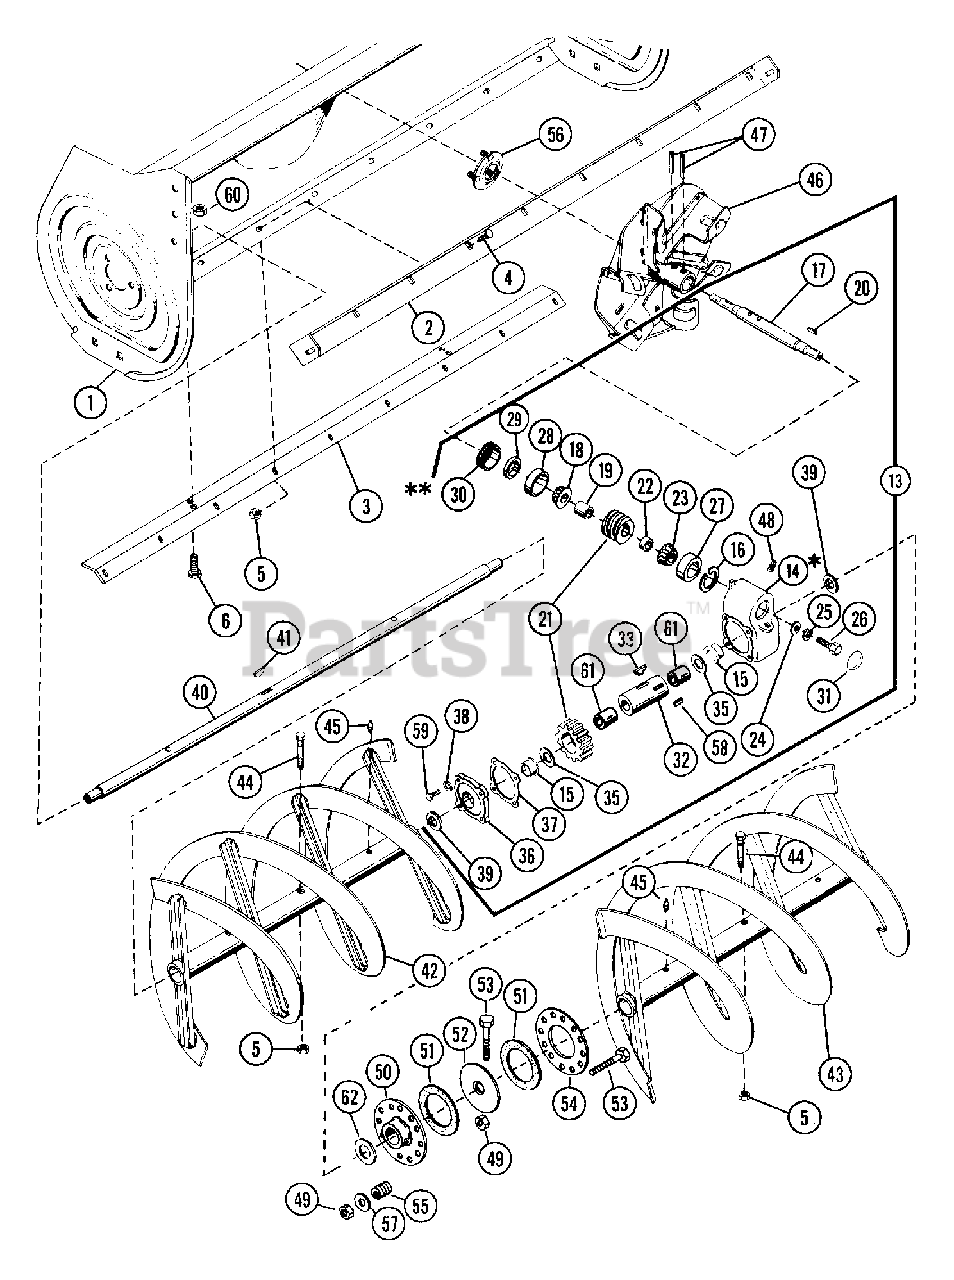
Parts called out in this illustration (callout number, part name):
1	BLOWER HOUSING ASSEMBLY
2	SCRAPER BLADE
3	SCRAPER BLADE BRACE
4	BLT-RDHDSQNK .31-18X.75 GR5 PL
5	NUT-LK .312-18 GR A PL
6	BLT-HEX .38-16X.75 PL GR5
13	GEAR CASE - CAST IRON
14	GEAR CASE - CAST IRON
15	BSHG-FLG .683X1.87X1.68X2.250
16	RG-RTNG-INT 1.781X.062
17	WORM SHAFT
18	BRG-CONE 1.0X.58
19	BEARING SPACER 1.032X1.25X1.78
20	KEY-SQ .188X1.0X.188 SAE 8630
21	WORM & GEAR SERVICE ASSEMBLY
22	BSHG, SPCR .755X1.12X.50 PM
23	BRG-CONE .750X.61
24	WSHR-FL-STL .328X1.0X.094
25	WSHR-LK .312X.097 PL HVY
26	BLT-HEX .31-18X.75 PL GR2
27	BRG-CUP 1.781X.475
28	BRG-CUP1.980X.420
29	SEAL 1.125X1.375X.125
30	ADJUSTMENT PLUG
31	DUST CAP
32	GEAR CASE SHAFT
33	KEY-FTHR .25X.875X.25 SAE 8630
35	WSHR-FL-STL 1.625X2.500X.012
36	GEAR CASE COVER
38	WSHR-LK-EXT. 250 ID
39	SEAL 1.625X2.125X.250
40	RAKE SHAFT
40	48 INCH RAKE SHAFT
41	KEY-WDRF .25X.875X.375 SAE A
42	RAKE, RIGHT-48(1.12ID X 15.75)
43	RAKE, LEFT-48"(1.12ID X 15.75)
44	SHEAR BOLT & NUT ASSEMBLY
44	BLT-HEX .31-18X2.00 PL GR5
45	SPIN DRIVE ZERK FITTING
47	PIN-ROLL .313X1.75
48	PIPE PLUG
49	NUT-LK-TOP .312-18 GR C PL
50	DRIVER
51	FRICTION DISC
52	DRIVEN PLATE
53	BLT-HEX .31-18X2.00 PL GR5
54	PRESSURE PLATE
55	SG-COMP .156X.665X.75
56	BEARING FLANGE
57	WSHR-FL-STL .323X.625X.062 PL
58	KEY-SQ .25X.625X.375
59	BLT-HEX .25-20X.75 PL GR2
60	NUT-LK TOP .375-16 GR C YWZC
61	BSHG-SLV 1.125X1.250X1.000
62	WSHR-FL-NYL 1.625X2.500X.060
